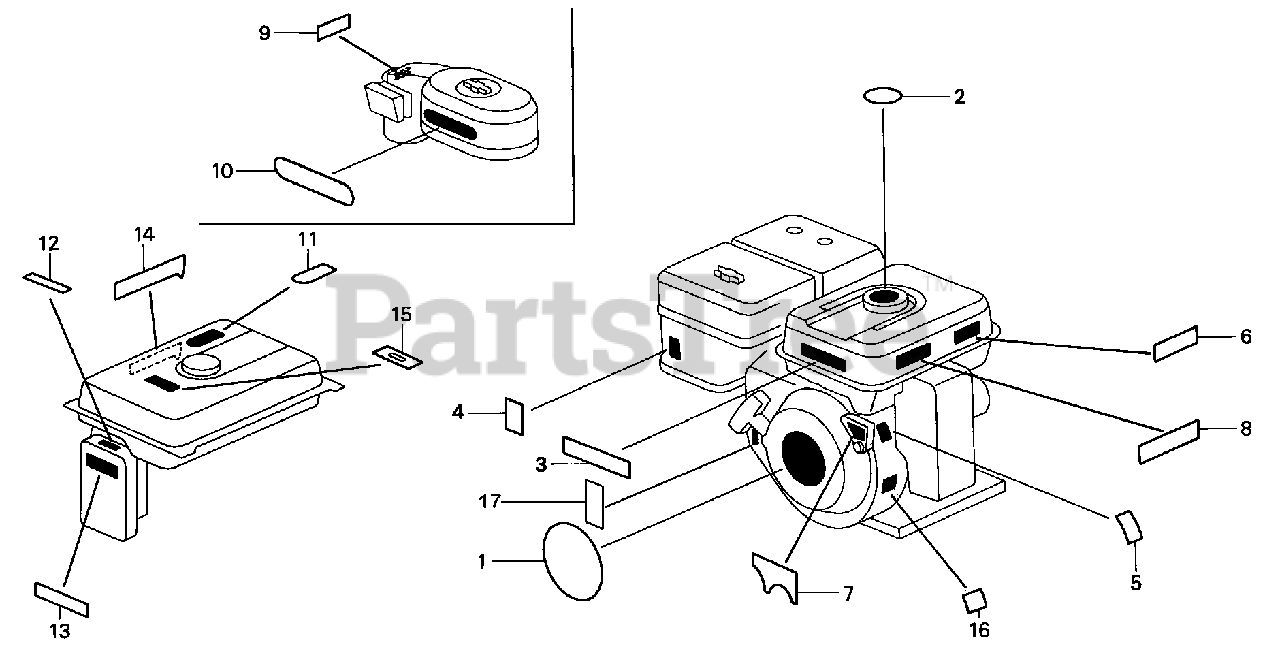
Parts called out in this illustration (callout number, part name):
1	EMBLEM (INTERNAL)
11	MARK, CAUTION (ENGLISH/FRENCH)(SPANISH)
12	MARK, CHOKE
13	MARK, AIR CLEANER
14	MARK, EX. CAUTION (ENGLISH/FRENCH)
15	PLATE, FUEL INDICATION
16	MARK, OIL CAUTION
